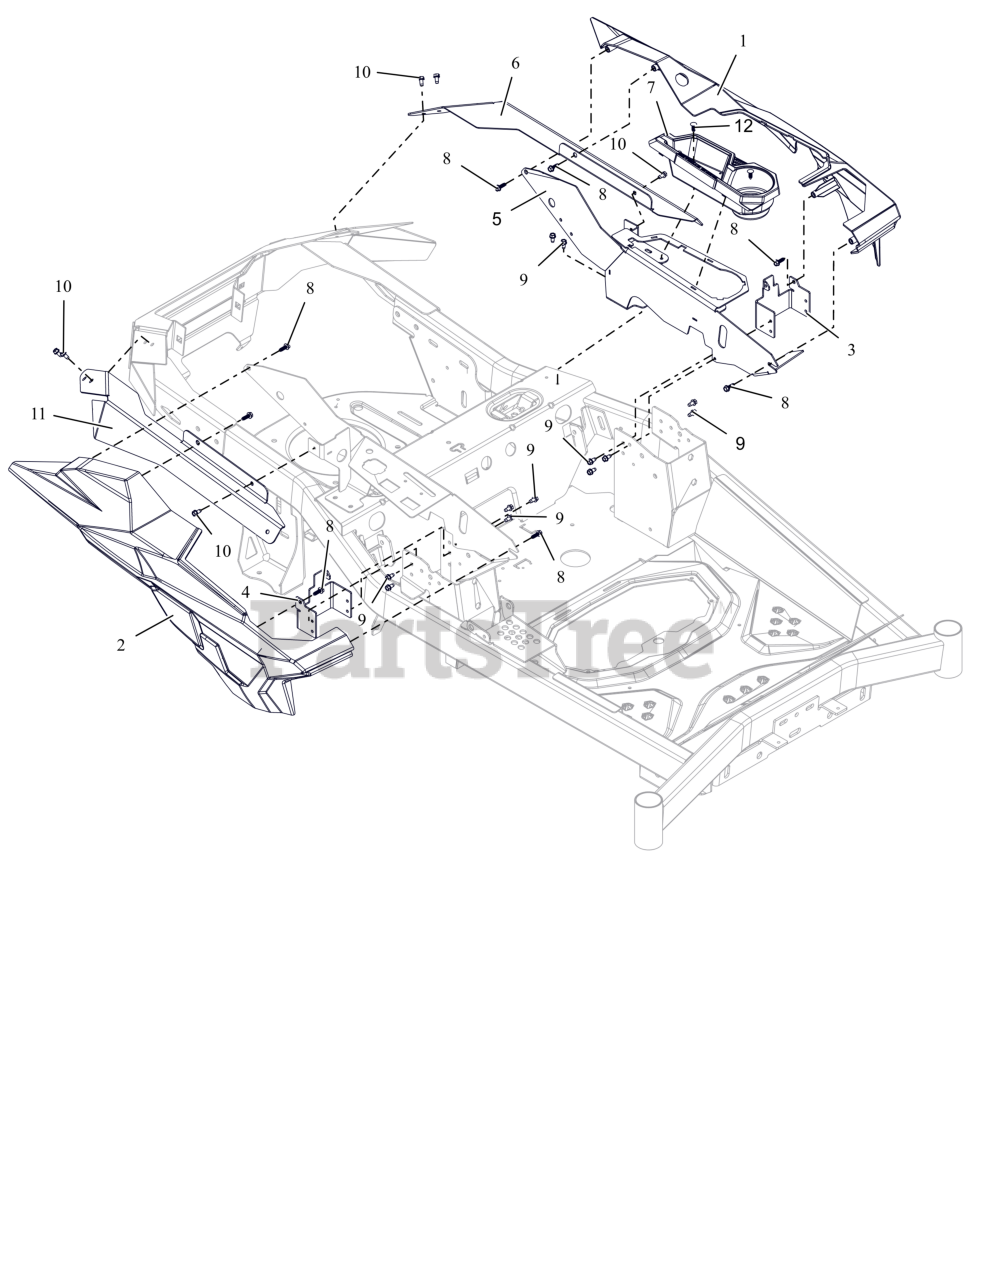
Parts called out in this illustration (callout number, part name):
1	KIT-LH GRAVELY FENDER W/ DECAL
2	FENDER- RH-GRAVELY
3	BRKT, FRONT FENDER MOUNT(LH) (BLACK)
4	BRKT, FRONT FENDER MOUNT(RH) (BLACK)
5	PANEL- CONTROL-LH-GRAVELY
6	BRKT- FENDER MOUNT-LH
7	HOLDER- CUP - GRAVELY
8	SCR, PLASTITE-HWH 0.25 X 0.75 ZC120
9	SCR-TAP .25-20X.50 HWH ZCC
10	SCR-TAP .25X.50 HWH ZB500
11	BRKT- FENDER MOUNT-RH
12	RIVET, .25 NYLON PANEL
